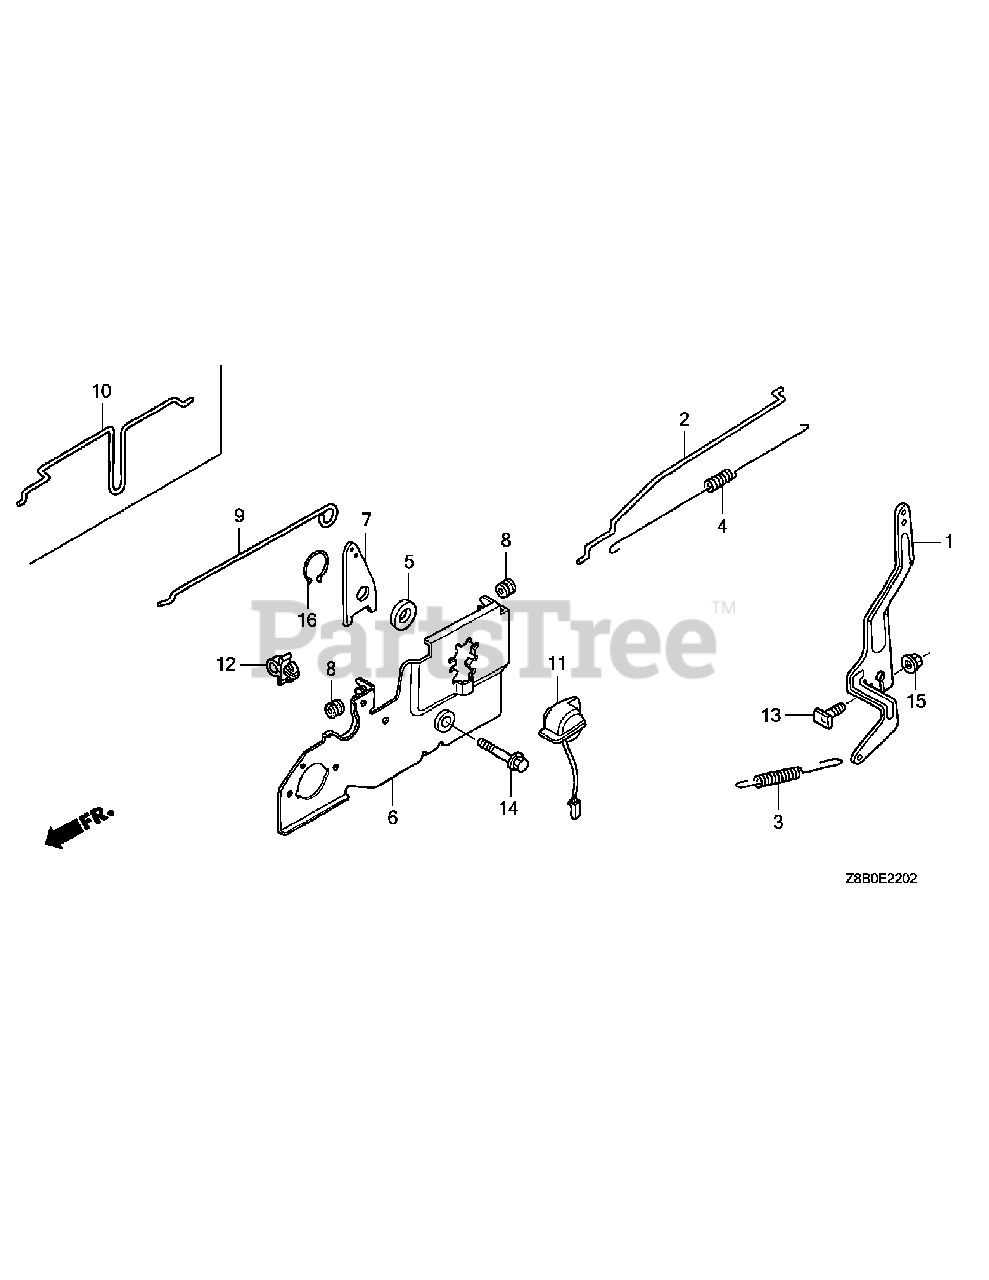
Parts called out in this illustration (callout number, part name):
1	ARM, GOVERNOR
2	ROD, GOVERNOR
3	SPRING, GOVERNOR
4	SPRING, THROTTLE RETURN
5	SPACER, CONTROL LEVER
6	BASE COMP., CONTROL
7	LEVER, CHOKE
8	GROMMET, CHOKE ROD
9	ROD, CHOKE
10	ROD, CHOKE
11	SWITCH ASSY., ENGINE STOP
12	HOLDER, WIRE (FASTEX)
12	CLIP A, CABLE (NIFCO)
13	BOLT, GOVERNOR ARM
14	BOLT, FLANGE, 6X45(CT200)
15	NUT, FLANGE, 6MM
16	CIRCLIP, EXTERNAL, 14MM
